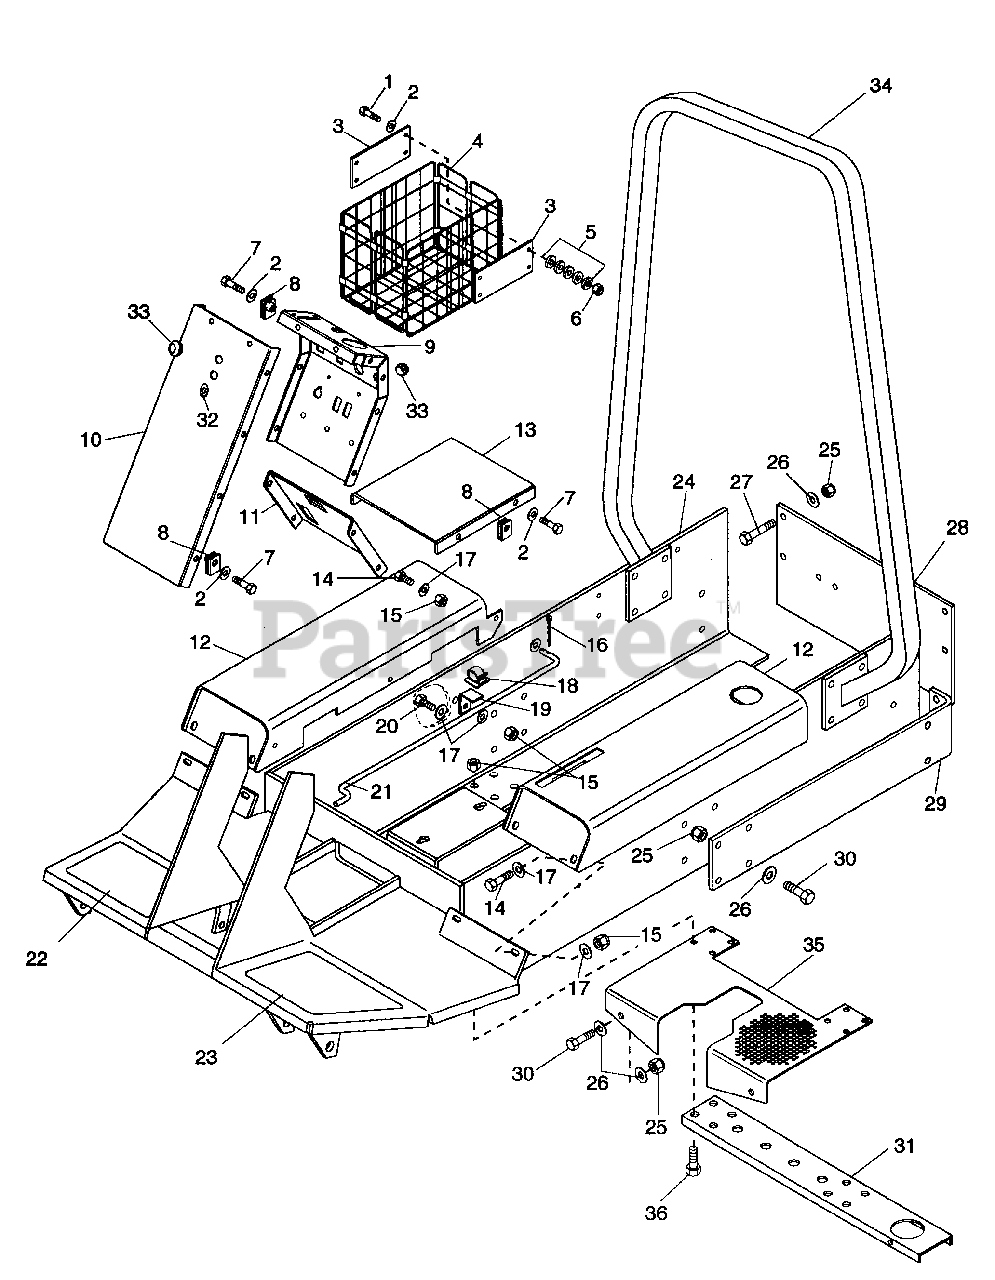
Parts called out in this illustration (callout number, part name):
1	BLT-HEX .25-20 X 1.50 PL GR 5
2	WSHR-FL-STL .563 X .375 X .109
3	STRP-BASKET
4	BASKET
5	WSHR-FRICTION .750 X .256 X .100
6	NUT-LK-NYL .250-20 PL
7	SCR-MCH .25-20 PAN HD
8	NUT-RTNR .25-20 X .56
9	PNL, INST SILK SCREEN
10	PNL, FRONT
11	PNL, BRAKE LOCK SILK SCRN
12	WLDMT, FENDER R.H.
12	WLDMT, FENDER L.H.
13	PLT, ACCESS SILKSCREEN
14	BLT-HEX .380-16 X .875
15	NUT-LK-NYL .375-16 PL
16	PIN-COTR .09 X .75 PL
17	WSHR-FL-STL .406 X .812 X .065
18	CLIP, WIRE
19	BRKT, STAY ROD
20	BLT-HEX .38-16 X 1.00 PL GR 5
21	ROD, STAY
22	CVR, R.H. FOOT
23	CVR, L.H. FOOT
24	WELDMENT, FRAME
25	NUT-LK-NYL .50-13 PL
26	WSHR-FL-STL .531 X 1.062 X .095
27	BLT-HEX .50-13 X 1.50 PL GR 5
28	PLT, BUMPER
29	BUMPER
30	BLT-HEX .50-13 X 1.25 PL GR 5
30	BLT-HEX .50-13 X 1.75 PL GR 8
31	BR, FRAME
32	WSHR-FL-STL .328 X 1.0 X .094 PL
33	GROMMET
34	WLDMT, ROLLOVER BAR(50)
35	SCREEN
36	BLT-HEX .38-16 X 1.25 PL GR 5
NS	DECAL, DANGER HAND
NS	DECAL, CORNER
NS	DECAL SET, PM 400
